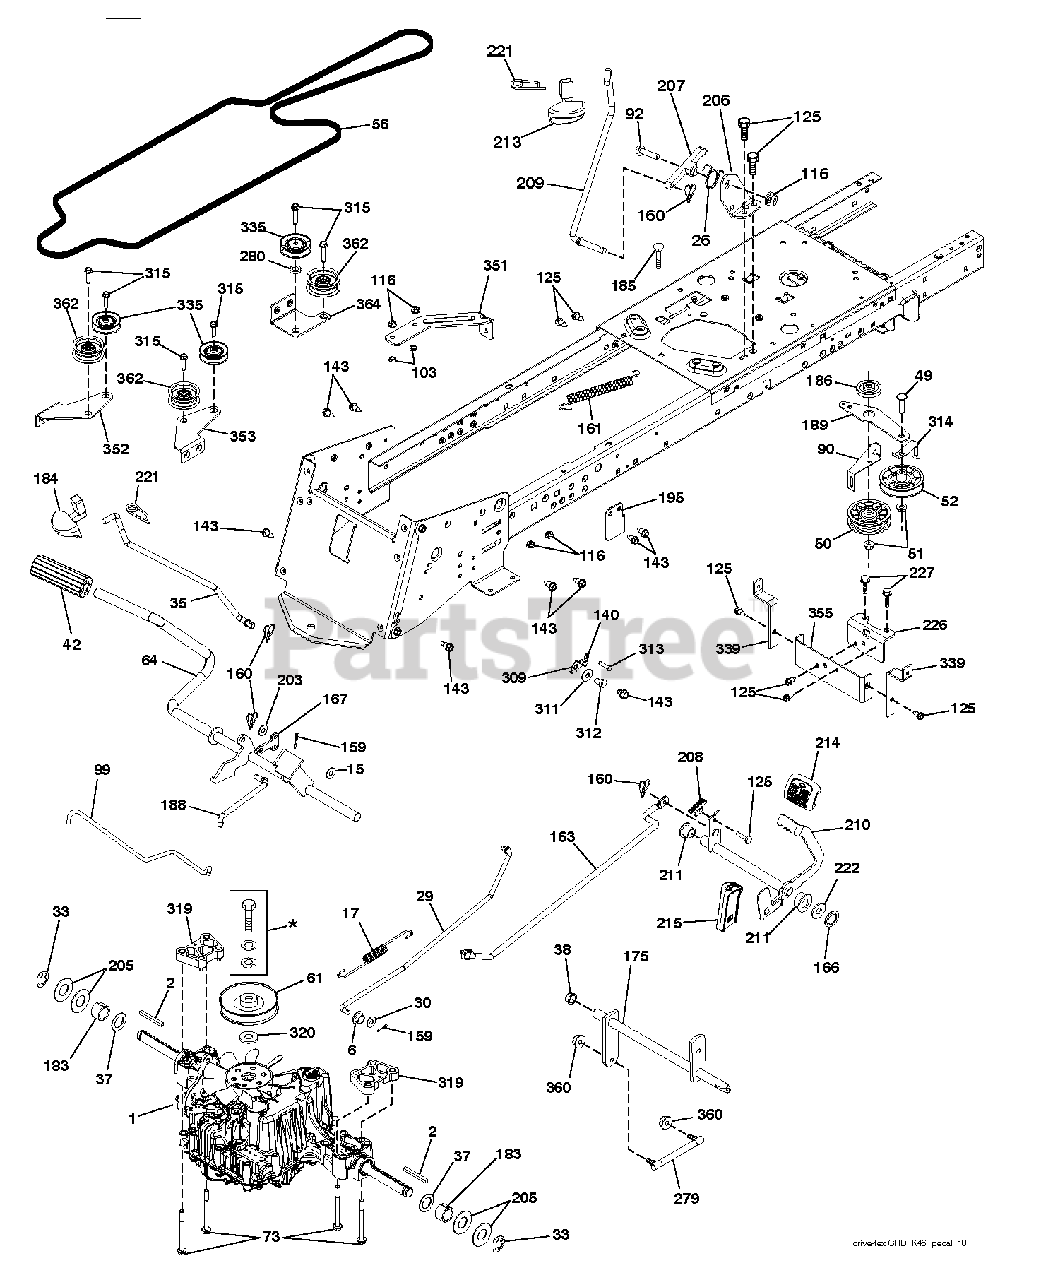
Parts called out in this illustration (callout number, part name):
17	Spring Brake
26	SPRING.RETURN.CRUISE
29	ROD
30	WASHER
35	ROD.BRAKE.PARTK.HUSQ.TEX
37	WASHER.HARDENED
38	NYLINER SNAP 5/8" ID
42	PEDAL COVER T
49	BOLT
50	IDLER.FLAT.910.OFFSET
51	NUT LOCK FLG 3/8-16 UNC
52	IDLER.V-GROOVE.910.OFFSET
56	V BELT DELV 113 K46 C
61	Transaxle Pulley
64	SHAFT.ASM.PEDAL.BRK.CNTR
73	BOLT.HEX.FLNG.5/16-18X3.75
90	KEEPER KEEPER BELT CL
92	BOLT
99	ROD ROD BYPASS CRD TE
116	NUT LOCK HEX FLANGE 5/16-18
125	SCREW
140	LOCKWASHER
159	COTTER PIN
160	RETAINER CLIP
161	SPRING, RETURN LT
163	ROD
167	LATCH.BRAKE.SPRING
175	SHAFT SUBASM.SHAFT.CR
184	HANDLE.PARKG.BRK.HUSQ/PRED.667
186	SPACER.RETAINER
188	LINK.CLUTCH.GROUND.DRIVE
189	BELLCRANK BELLCRANK G
203	WASHER
206	BRKT.MOUNT.LATCH.CRUIS
207	LATCH.CONTROL.CRUISE
208	GEAR.SECTOR.CONTROL.CR
209	ROD.CONTROL.CRUISE.GT.
210	ROCKER.ASM.PEDAL.CONTR
211	BEARING.NYLON
213	KNOB.CONTROL.CRUSIE.HU
214	PAD PEDAL FORWARD
215	PEDAL RUBBER REVERSE
221	RETAINER.SPRING.CLIP.H
222	WASHER 21/32 X 1-1/4 X 10 GA.
226	BRACKET.MOUNT.TORQUE.K46.TLT
227	SCREW
279	LINK SUBASM. LINK AND STUD
309	PLATE FASTENING LT
315	BOLT.5/16-18X1.25
319	SPACER SPACER TRANSAX
320	WASHER.SPACER.MANDREL
335	PULLEY.V-IDLER.
339	STRAP STRAP TORQUE K4
351	BRACKET BRACKET DECK
352	Idler Bracket
353	Bracket
355	STRAP STRAP TORQUE K4
360	NUT NUT HEX CENTERLOC
362	IDLER.FLAT.2.25.INCH
364	BRACKET BRACKET IDLER
